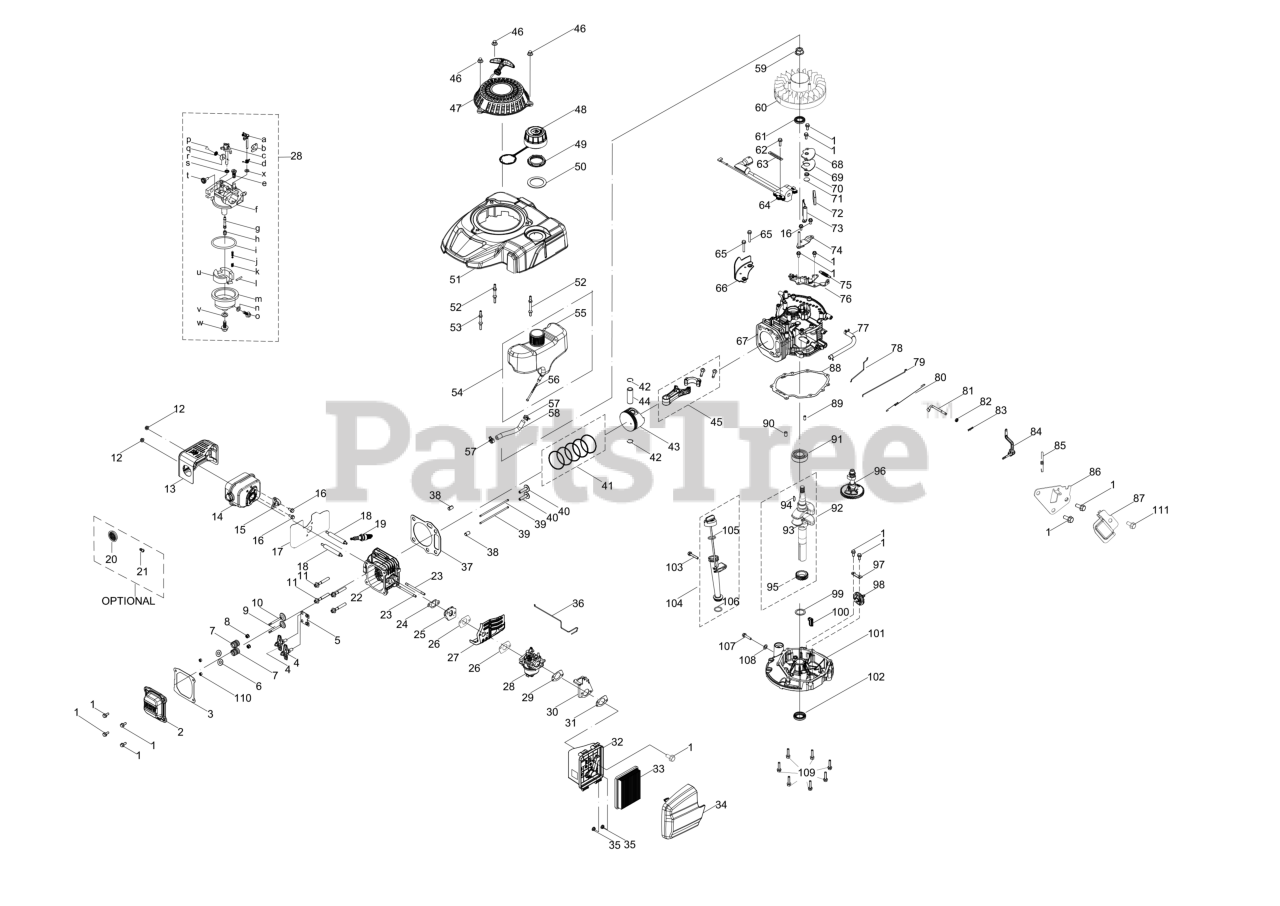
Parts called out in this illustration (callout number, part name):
1	BOLT M6-1 x 14 GR8.8
2	VALVE COVER
3	VALVE COVER GASKET
5	ROCKER ARM BASE
6	VALVE SPRING SEAT
7	VALVE SPRING
8	INTAKE VALVE SEAL
9	EXHAUST VALVE
10	INTAKE VALVE
11	BOLT-M8 x 54
13	MUFFLER SHIELD
14	MUFFLER ASSEMBLY
15	CHOKE TEMP CONTROL THERMOSTAT
16	BOLT M6-1 x 12 GR8.8
17	MUFFLER GASKET
18	STUD M6-1 x 95
19	SPARK PLUG (F5RTC/RN11YC4/BPR5ES)
20	SPARK ARRESTOR
21	SCREW M3.5 x 9.5
22	CYLINDER HEAD
23	STUD M6 x 90
24	CARBURETOR INSULATOR GASKET
25	CARBURETOR INSULATOR
26	CARBURETOR GASKET
27	CARB HEAT SHEILD
28	CARBURETOR
29	AIR FILTER BRACKET GASKET
30	AIR FILTER BRACKET
31	AIR FILTER BASE GASKET
32	AIR FILTER BASE
33	AIR FILTER
34	AIR FILTER COVER
36	CHOKE TEMP CONTROL LINKAGE
37	HEAD GASKET
38	PIN (10MMx16MM)
41	PISTON RING SET
42	WRIST PIN CLIP
45	CONNECTING ROD
46	ACORN NUT M6-1
47	RECOIL STARTER ASSEMBLY
48	FUEL CAP W/TETHER
49	FUEL TANK NUT
50	FUEL TANK GROMMET
51	ENGINE SHROUD W/O IGNITION SWITCH
52	STARTER/SHROUD REAR STUD
53	STARTER/SHROUD FRONT STUD
54	Not Serviceable/ Components Only
56	FUEL FILTER
57	CARBURETOR HOSE CLAMP
59	FLYWHEEL NUT M14-1.5
61	UPPER CRANKSHAFT SEAL
62	BOLT M6-1 x 20 GR8.8
63	FLEXIBLE CLAMP
64	IGNITION COIL ASSEMBLY
65	BOLT M6-1 x 25 GR8.8
66	ENGINE BRAKE COVER PLATE
68	BREATHER COVER PLATE
69	BREATHER GASKET
70	BREATHER VALVE SPRING
71	BREATHER VALVE
72	BREATHER SCREEN
74	AIR VANE BRACKET
75	ENGINE BRAKE SPRING
76	ENGINE BRAKE ASSEMBLY
77	BREATHER HOSE ASSEMBLY
78	CHOKE LINKAGE
79	THROTTLE LINKAGE
80	THROTTLE LINKAGE SPRING
81	GOVERNOR ARM SHAFT
84	GOVERNOR ARM ASSEMBLY
85	GOVERNOR SPRING
86	COMPONENT BRACKET
87	GOVERNOR SHIELD
88	CRANKCASE COVER GASKET
89	DOWEL PIN 7 X 14
90	DOWEL PIN 9 X 14
92	CRANKSHAFT
93	CRANKSHAFT
94	WOODRUFF KEY
95	TIMING GEAR
96	CAMSHAFT ASSEMBLY
97	GOVERNOR GEAR MOUNTING PLATE
98	GOVERNOR GEAR
99	THRUST WASHER
100	OIL RETURN SEAL
101	CRANKCASE COVER
102	LOWER CRANKSHAFT SEAL
103	BOLT M6-1 x 35 GR8.8
104	DIPSTICK ASSEMBLY
107	OIL DRAIN PLUG
108	FLAT WASHER
109	BOLT-M6-1 x 28 GR8.8
111	BOLT M6-1 x 10 GR8.8
S	Throttle/Choke Shaft Fiber O-Ring
